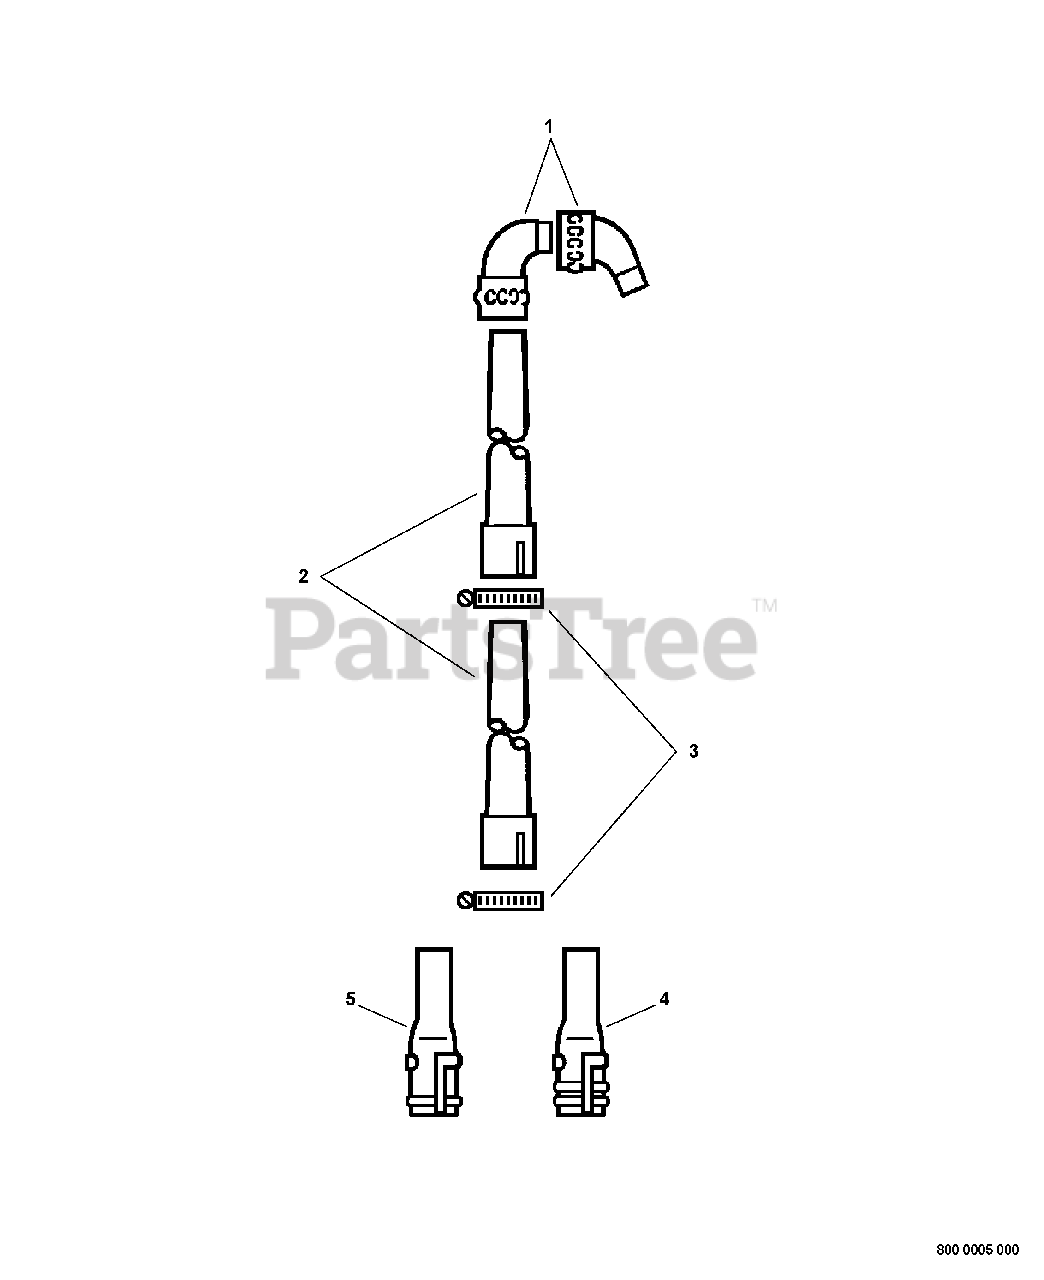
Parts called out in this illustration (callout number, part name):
1	TUBE, BLOWER - ELBOW
2	TUBE, BLOWER - STRAIGHT
3	CLAMP
